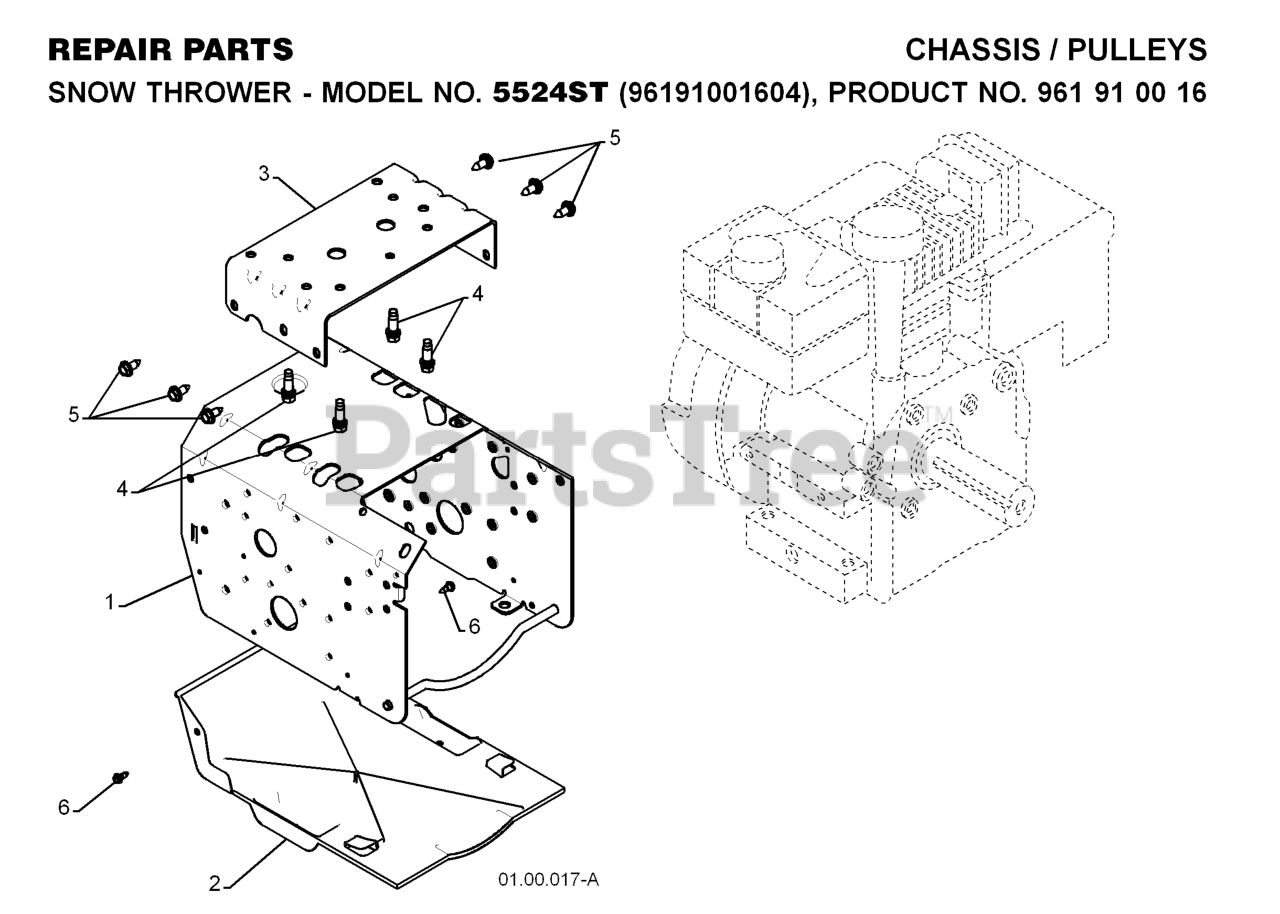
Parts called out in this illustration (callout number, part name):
1	FRAME.WELD.PNT.003BGP
2	PAN.BOTTOM.PLASTIC
3	PLATE.ENGINE.MOUNT.PNT
4	BOLT 3/8-16X1-1/8
5	SELF-TAPPING SCREW 5/16-18X3/4
6	SCREW, HEX HEAD, TAPPING
